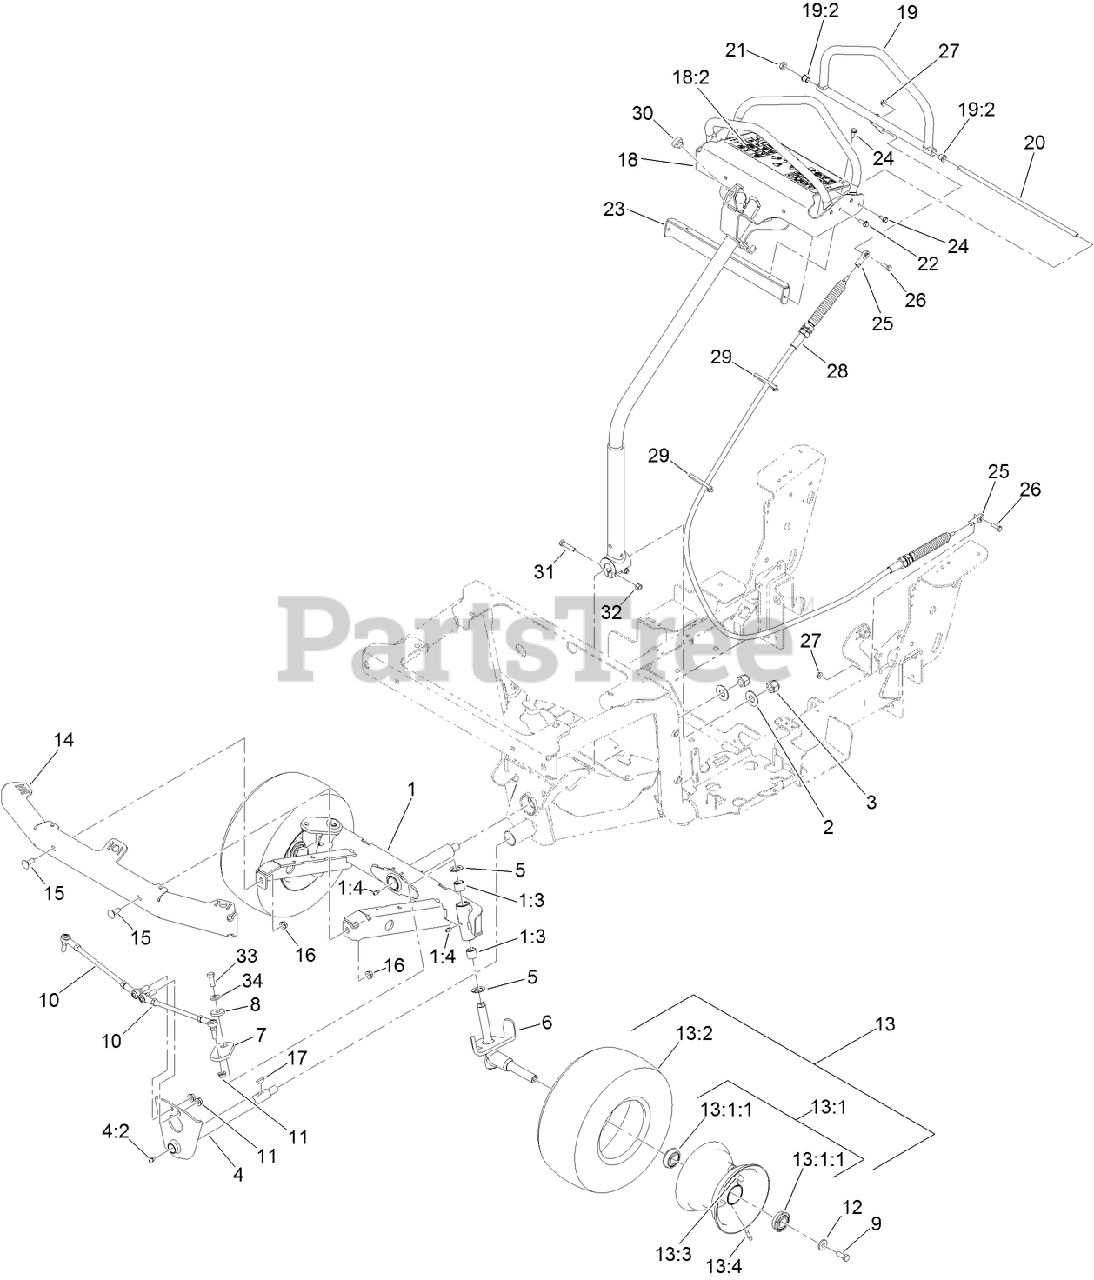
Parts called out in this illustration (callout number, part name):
1	FRONT AXLE ASM
1:3	BEARING-SLEEVE
1:4	ZERK-GREASE
2	WASHER-FLAT
3	NUT-HEX, NI
4	STEERING SHAFT ASM
4:2	ZERK-GREASE
5	WASHER-THRUST
6	FRONT AXLE ASM
7	ARM-STEERING
8	WASHER
9	SCREW-HH
10	STEERING LINKAGE ASM
11	NUT-HF
12	SPACER
13	WHEEL AND TIRE ASM
13:1	WHEEL ASM
13:1:1	BEARING
13:3	STEM-VALVE
13:4	FITTING-GREASE
14	BUMPER-FRONT
15	SCREW-CARR
16	NUT-HF
17	KEY-WOODRUFF
18	MOTION HANDLE ASM
18:2	DECAL-WARNING
19	MOTION HANDLE ASM
19:2	BEARING
20	SHAFT-PIVOT, SPEED CONTROL
21	SPACER-SHAFT, DRIVE LEVER
22	SCREW-HHF
23	PANEL-REAR, STEERING
24	SCREW-HWH
25	ROD END-BALL JOINT
26	SCREW-HH
27	NUT-HF
28	CABLE-MOTION
29	TIE-PLASTIC
30	BUMPER-RUBBER
31	SCREW-HH
32	NUT-HEX
33	SCREW-HH
34	WASHER-BELLEVILLE
